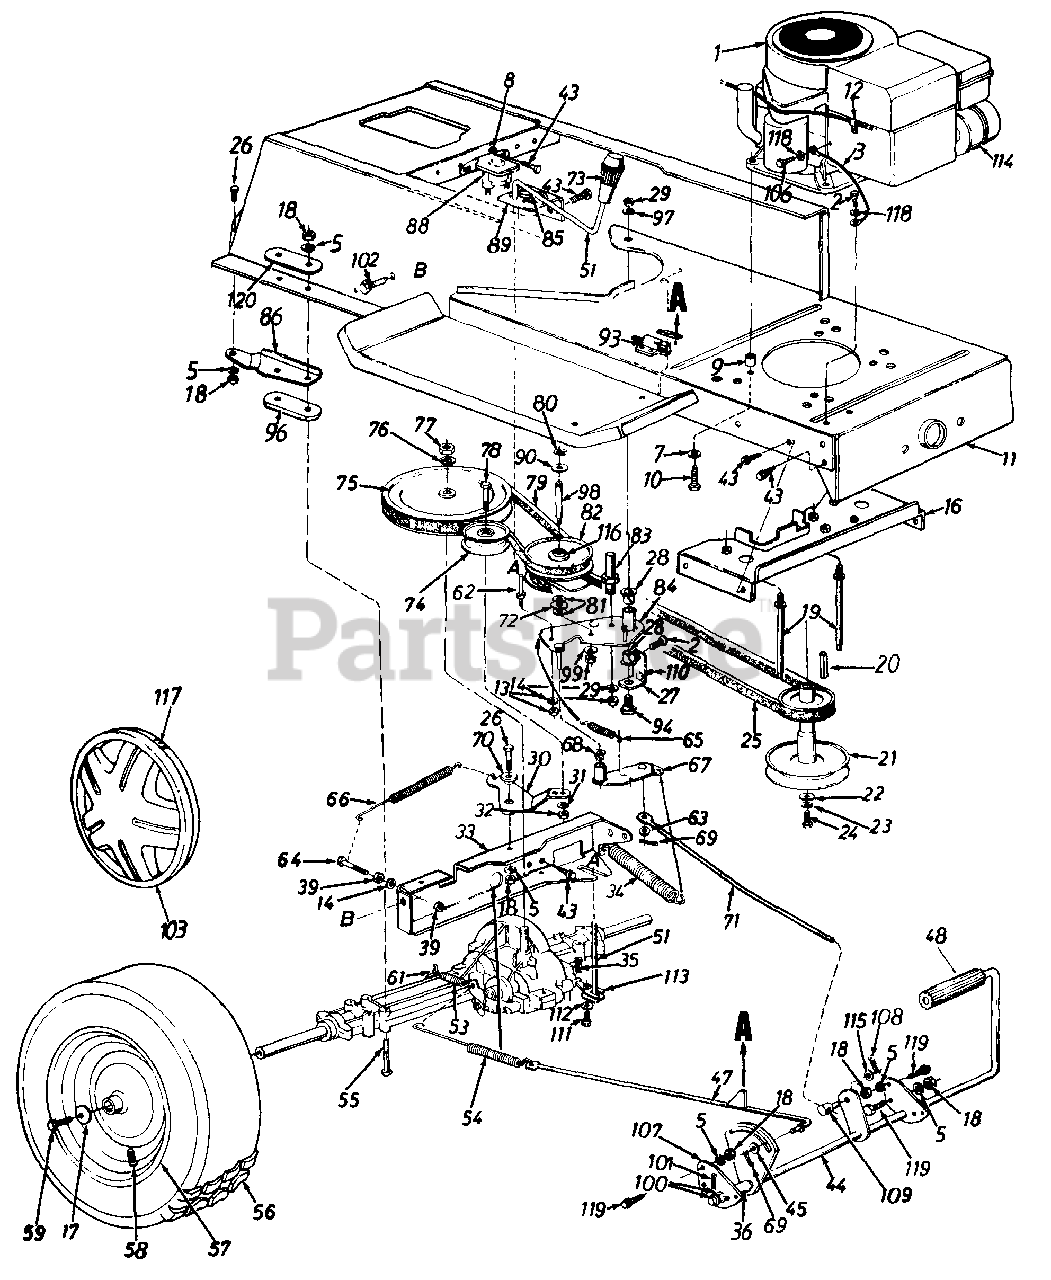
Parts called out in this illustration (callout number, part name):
1	Engine
2	Hex Wash. AB-Tap Scr. 5/16" x .75"
3	Electric Ground Wire
5	L-Wash. 5/16" I.D.
7	Fl-Wash .406" I.D. x 1.25"
8	Ext. L-Wash. 1/4" I.D.
9	Spacer
10	Hex Tap Scr. 3/8-16 x 1.5" Lg.
13	Hex Nut 1/4-20 Thd.
14	L-Wash. 1/4" I.D.
18	Hex Nut 5/16-18 Thd.
19	Belt Guard Stud 3.6" Lg.
20	Sq. Key 1/4" x 1/4" x 2.00"
21	Engine Pulley
22	Fl-Wash. 7/16" I.D. x 1.25"
23	L-Wash. 7/16" I.D.
24	Hex Bolt 7/16-20 x 1.50" Lg.
25	Variable-Speed Belt
26	Hex Bolt 5/16-18 x .75" Lg.
27	Bearing Shaft Bracket Ass'y.
28	Flanged Nyliner Brg .63" I.D. x .6" Lg.
29	Hex Nut 3/8-24 Thd.
31	L-Wash. 3/8" I.D.
32	Hex Nut 3/8-24 Thd.
35	Inter. Cott-Pin
36	Spacer .63" I.O.
39	Hex Nut 1/4-28 Thd.
43	Hex Wash. Hd. S-Tap Scr. 1/4-20 x .50" Lg.
47	Brake Rod Ass'y.
48	Foot Pad
51	Shift Lever Ass'y.
53	Ext. Spring .38" O.D. x 2.5"
54	Ext. Spring 7.08"
55	Hex Bolt 5/16-18 x 3.5" Lg.
56	Wheel Ass'y. Comp.
57	Wheel Rim Only
58	Air Valve (Service Only)
59	Hex Bolt 5/16-24 x .75" Lg.
61	Brake Return Spring Anchor
62	Belt Guard Pin 1/4-20 Thd.
63	Fl-Wash .34" I.D. x .68" O.D.
64	Hex Bolt 1/4-28 x 1.25" Lg.
65	Ext. Spring
66	Ext. Spring .62" O.D. x 6.12"
69	Cotter Pin 3/32" Dia.
70	Shoulder Spacer .27" Lg.
71	Speed Control Link
72	Truss Bearing .56 Dia. x 1.25"
73	Shift Knob
74	Fl-Idler Pulley 3.25" x .75"
75	"V"-Pulley
76	Bell-Wash .56" I.D. x 1.125"
77	Hex Jam Nut 9/16-18 Thd.
78	Hex Bolt 3/8-24 x 1.75" Lg.
79	Variable Speed Belt
80	Snap Ring .56" Dia.
81	Fl-Wash.
82	Variable Speed Pulley Ass'y. 5" O.D.
83	Belt Keeper 3" Lg.
90	Teflon Washer .565" I.D.
93	Safety Switch (Clutch)
94	Shld. Bolt 3/8-24 x 3.12" Lg.
96	Transaxle Spacer
97	Bell-Wash .38" I.D. x .88"
98	Shaft .56" Dia. x 3.875" Lg.
99	Bell-Wash .39" I.D. x 1.12"
100	Fl-Wash .64" I.D. x .94"
101	Cotter Pin 1/8" Dia. x 1.25"
102	Hex Wash. Hd. Scr. 5/16-18 x .62" Lg.
103	Hub Cap (Gray)
106	Pan Hd. Mach. Scr. 5/16-18 x .75" Lg.
109	Ferrule
110	Hex Bolt 5/16-18 x 1.0" Lg.- (Gr. 5)
111	Hex Bolt 1/4-28 x .50" Lg.
112	Bell-Wash .265" I.D. x .75"
113	Shift Lever Link Ass'y.
114	Muffler
115	Fl-Wash .385" I.D. x .62"
116	Needle Brgs.
117	Spring Clip
118	External L-Wash. 5/16" I.D.
119	Hex TT-Tap Scr. 5/16-18 x .75"
